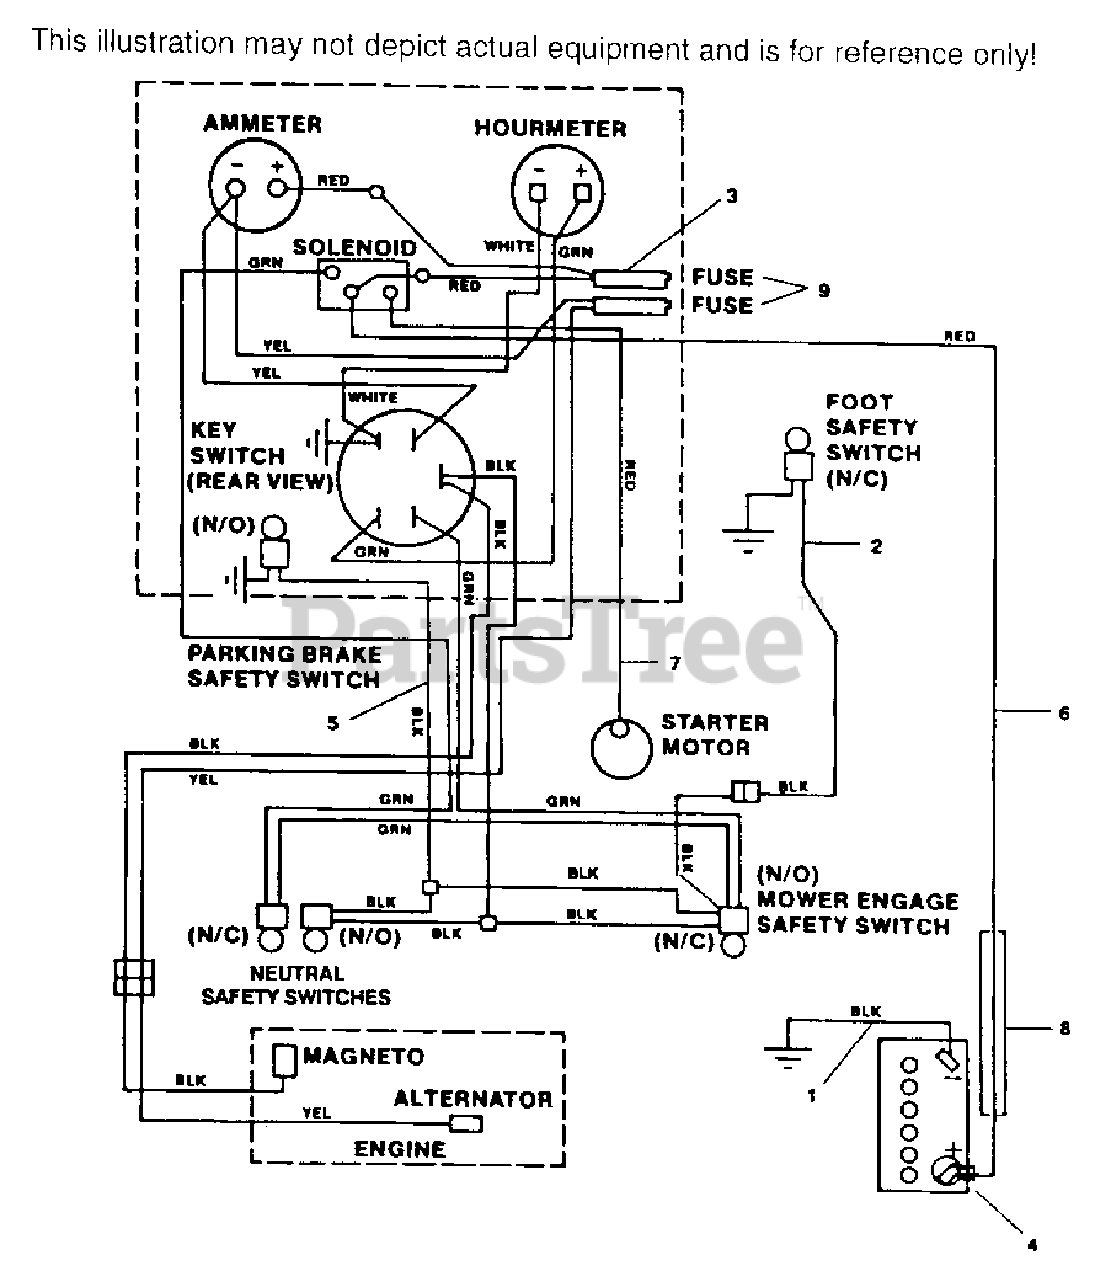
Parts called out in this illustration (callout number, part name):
1	BATTERY CABLE, GROUND
2	WIRE HARNESS, FOOT SAFETY SWITCH
3	WIRE HARNESS, SOLENOID TO AMMETER
4	RUBBER BOOT
5	WIRE HARNESS
6	BATTERY CABLE, LONG
7	BATTERY CABLE, SHORT
8	CONDUIT, BLACK NYLON
9	FUSE, 20 AMP BLADE TYPE AUTOMOTIVE
